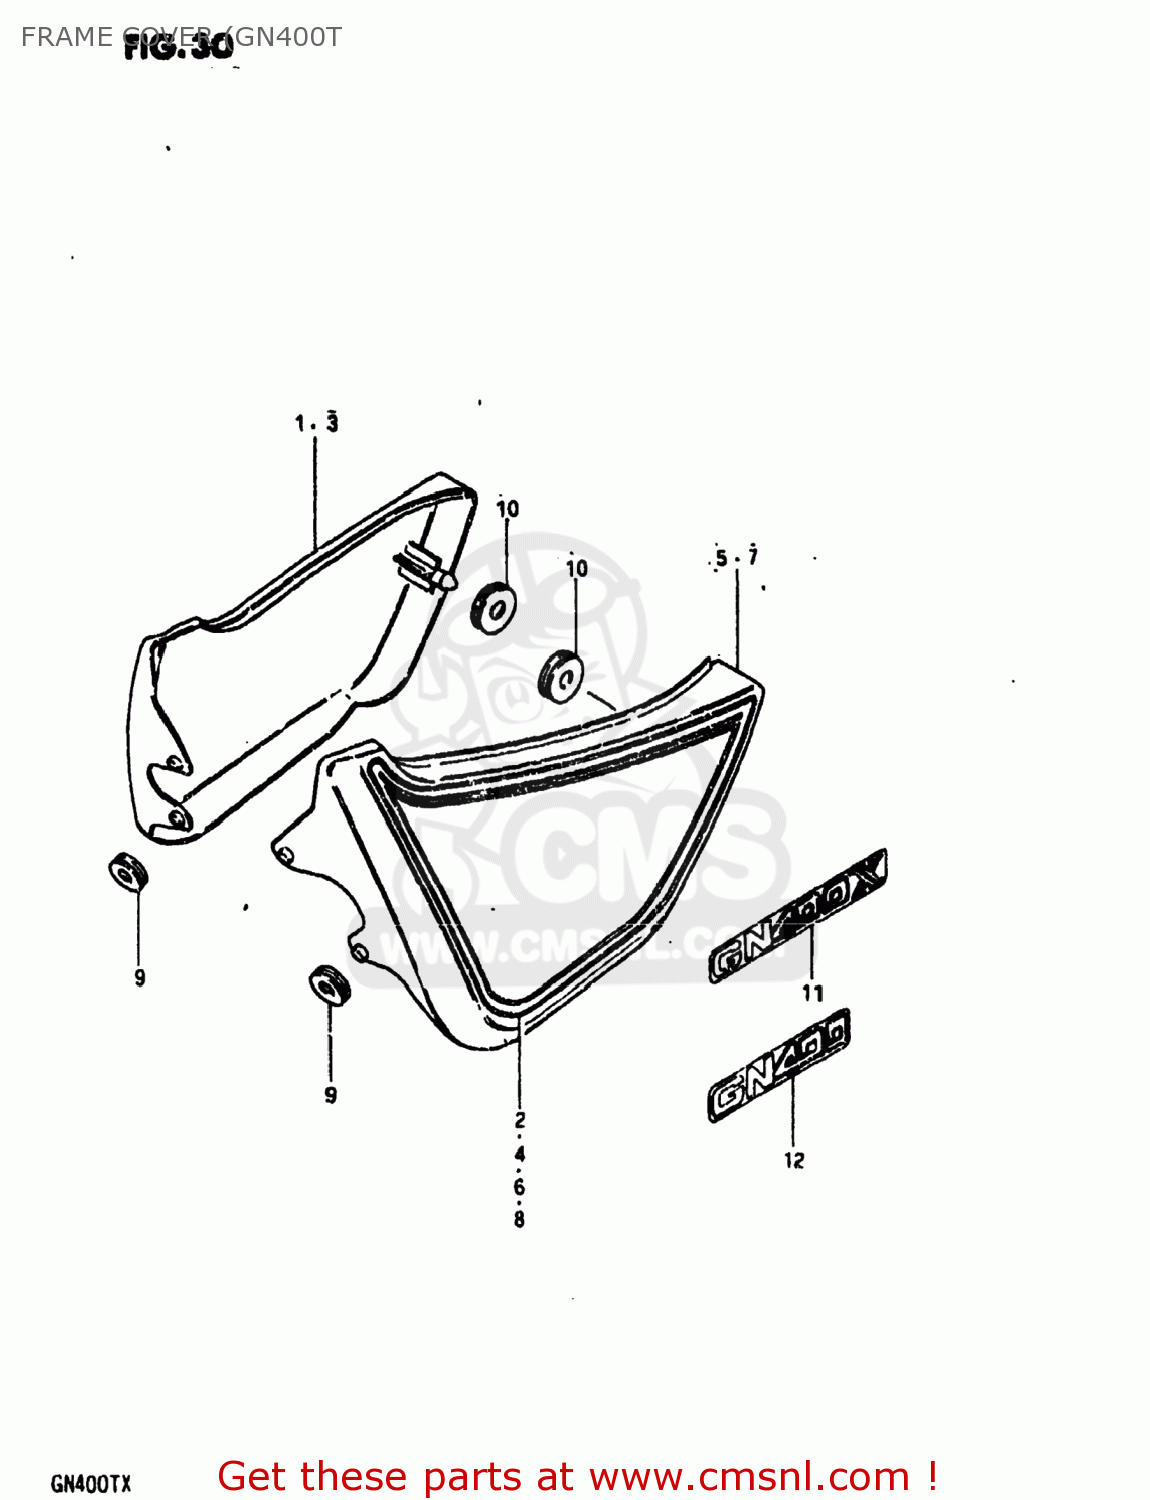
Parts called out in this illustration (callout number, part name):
1	COVER,FRAME,RIGHT
2	TAPE SET,FRAME COVER
3	COVER,FRAME,RIGHT
4	TAPE SET,FRAME COVER
5	COVER,FRAME,LEFT
6	TAPE SET,FRAME COVER
7	COVER,FRAME,LEFT
8	TAPE SET,FRAME COVER
9	CUSHION
10	CUSHION
11	EMBLEM
12	EMBLEM (GN400)
